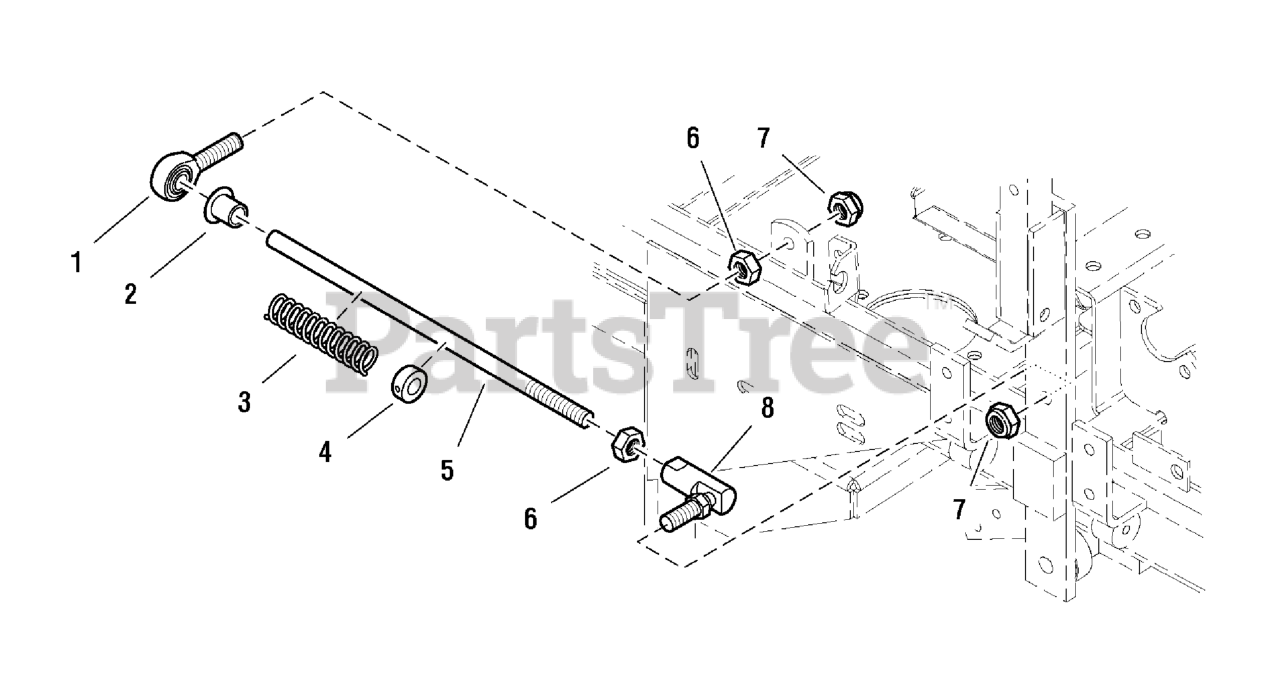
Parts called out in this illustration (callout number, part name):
1	BALL JOINT, 3/8-24 Male
2	BUSHING
3	SPRING, Compression
4	COLLAR, 3/8" Set
5	NEUTRAL CONTROL ROD
6	NUT, 3/8-24 Hex
7	NUT, 3/8-24 Hex Nylon Lock
8	BALL JOINT, 3/8" Female Studded
